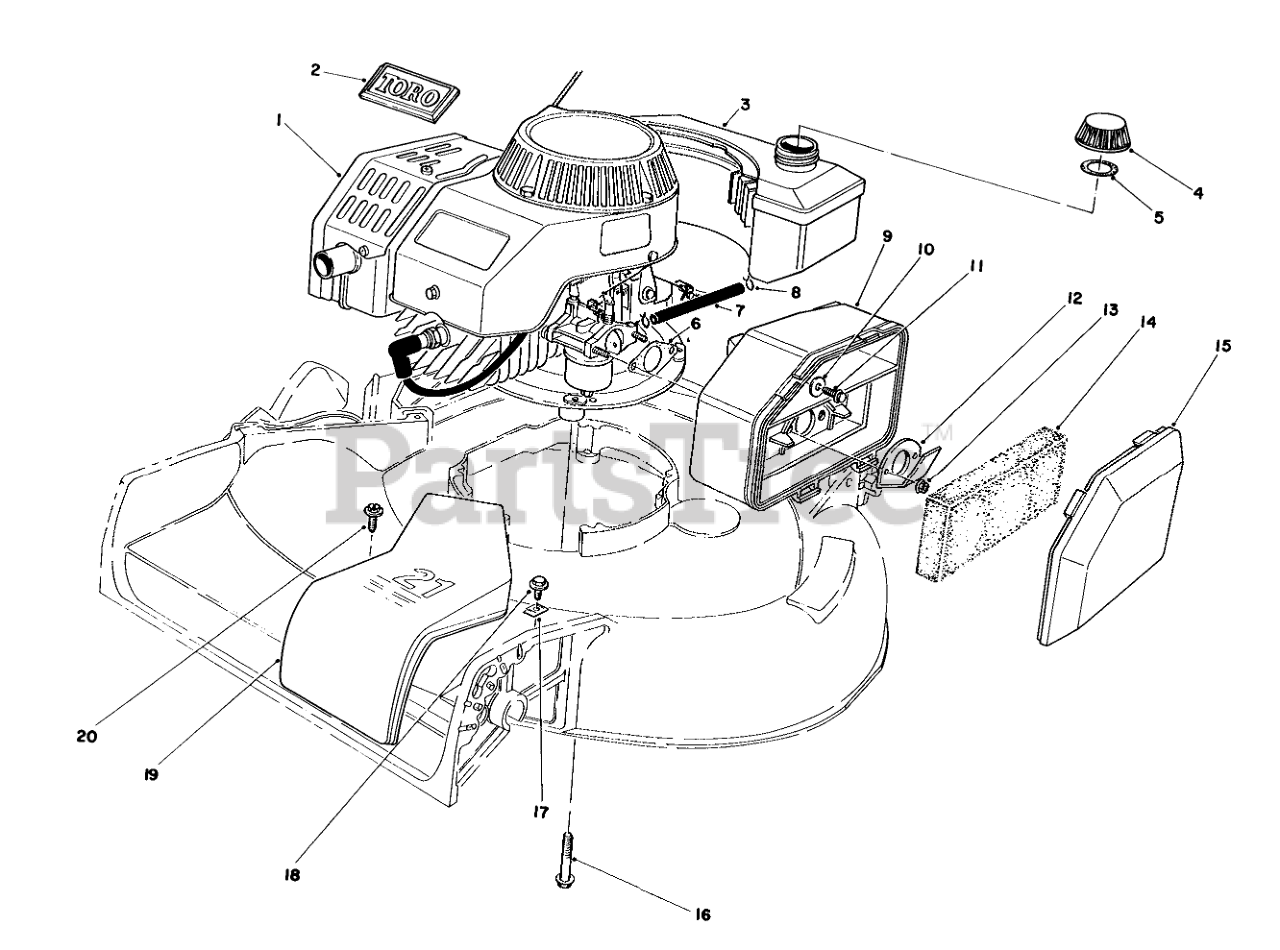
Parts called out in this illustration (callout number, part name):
1	Engine
2	TORO LOGO PLT
3	Fuel Tank Assembly
4	Gas Cap Assembly (Incl. Ref. #5)
5	GAS CAP GASKET
6	GASKET-AIR CLEANER
7	FUEL LINE
8	CLAMP-HOSE
9	AIR CLEANER
10	WASHER-FLAT
11	Screw Washer Head
12	SPIT BACK DEFLECTOR
13	NUT-LOCK
14	FILTER
15	AIR CLEANER COVER
16	FLG SCREW,3/8-16X2.000
17	Cable Clamp
18	SCREW-HWHTF
19	BELT COVER 21" S D
20	SCREW
